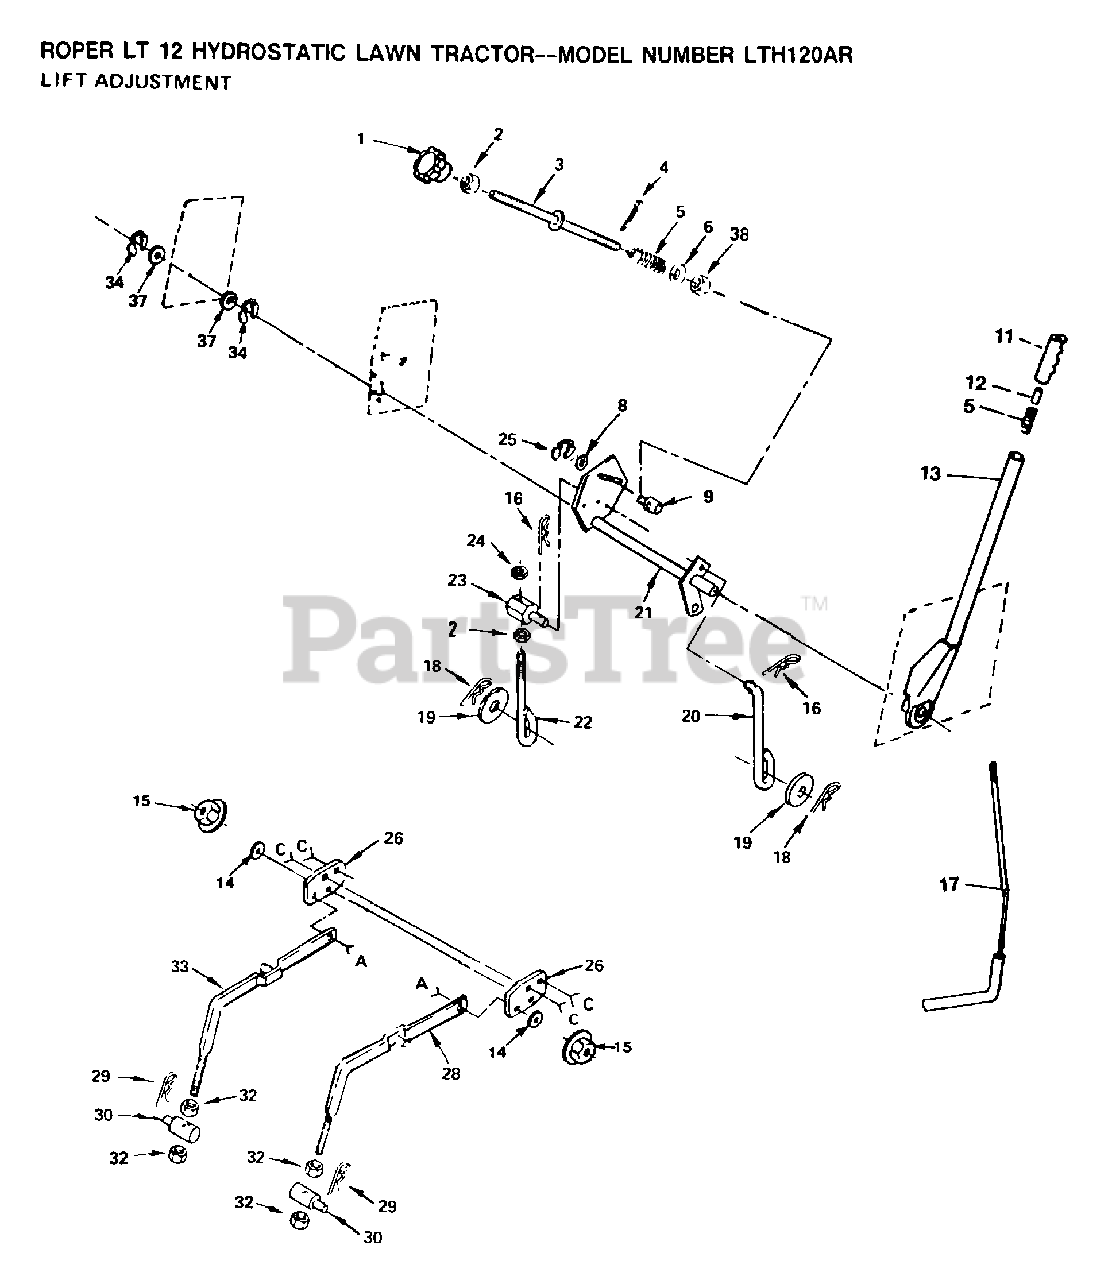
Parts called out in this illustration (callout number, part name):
2	NUT.HEX.3/8-16UNC
3	ROD LIFT LT
5	SPRING T
6	WASHER
8	WASHER
9	TRUNION LT
10	"BOLT, SHOULDER LT"
11	GRIP
14	WASHER T
15	NUT SPECIAL T
17	LEVER ROD LT
18	SPRING.RETAINER
20	LIFT LINK LT
22	LINK LIFT LT
25	KLIP RING
26	"BRACKET, SUSPE T"
29	SPRING H
32	NUT
34	E-RING
36	BOLT
37	WASHER
38	NUT T
